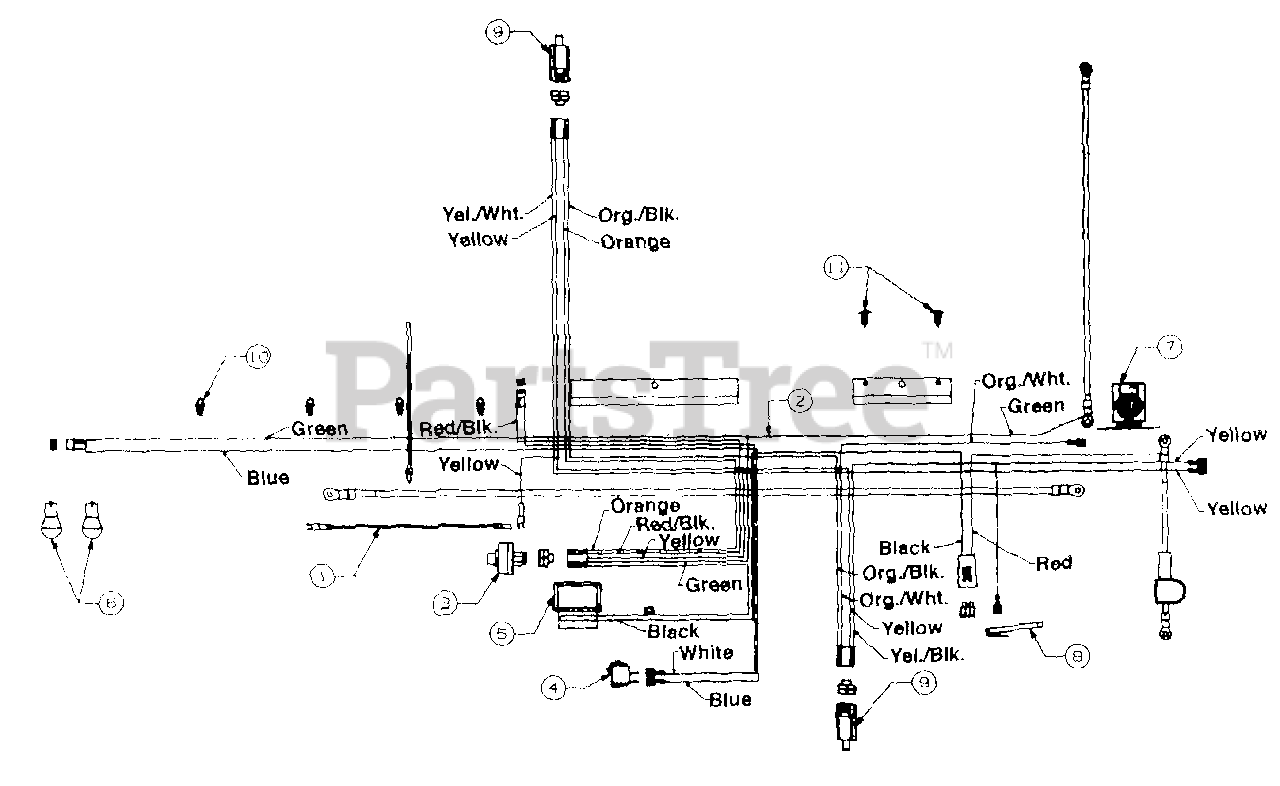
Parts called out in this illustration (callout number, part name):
1	Harness Adapter
2	Wire Harness wl Light Switch and Amp
3	Ignition Switch
4	Light Switch
5	Ammeter
6	Bulb
7	Solenoid
8	Safety Switch (Reverse)
9	Safety Switch
10	Wire Retainer Clip
